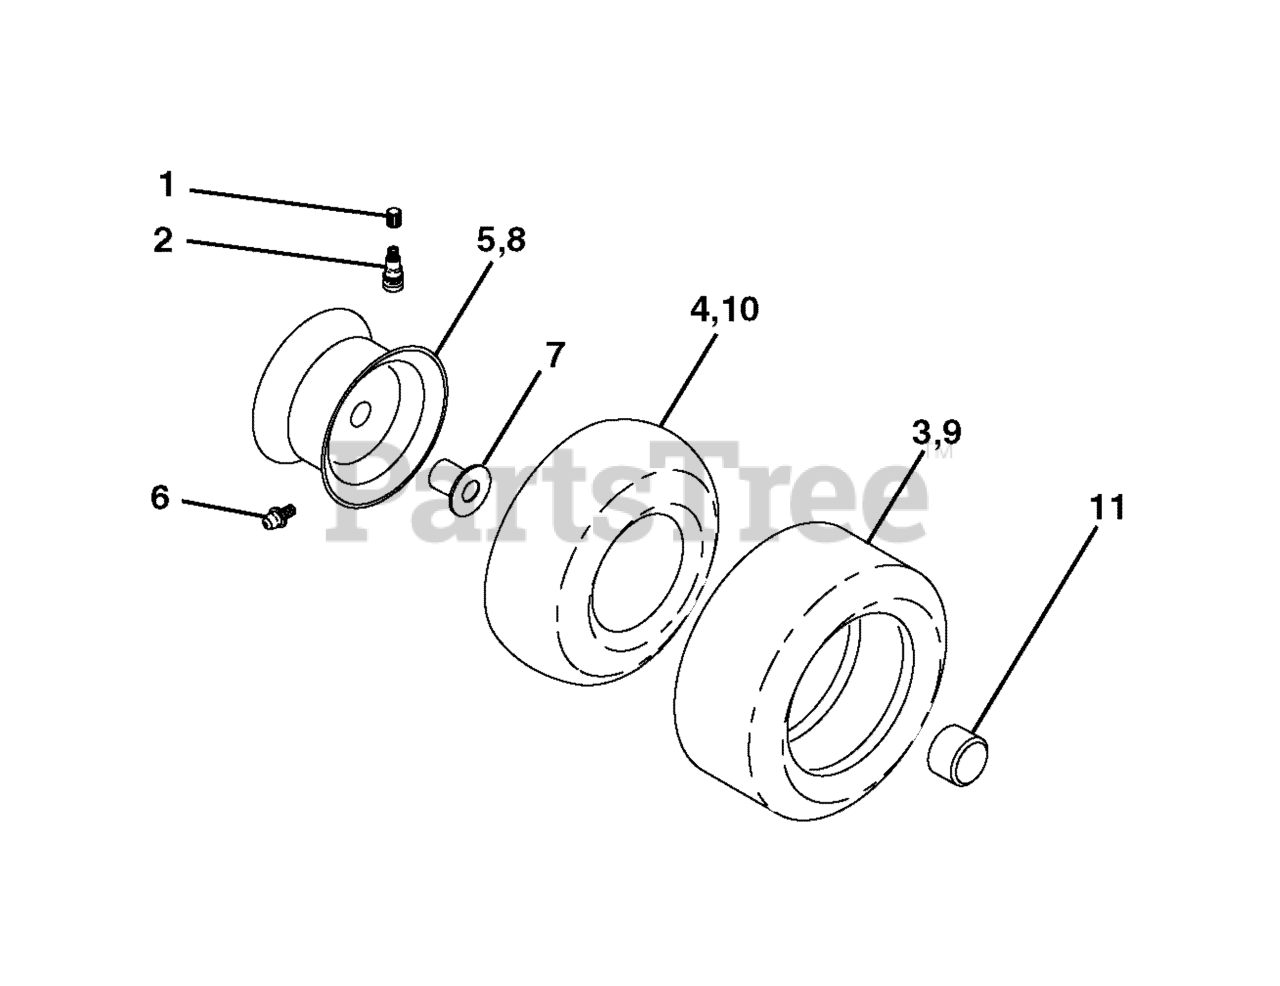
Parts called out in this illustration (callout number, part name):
1	Valve Cap, Tire
2	Stem, Valve
3	Tire, Front, 15 x 6.0-6
4	Tube, Front Tire
5	Rim, Front
6	Fitting, Grease
7	Bearing, Flange
8	Rim, Rear
9	Tire, Rear, 20 x 8-8
10	Tube, Rear Tire
11	Cap, Axle
